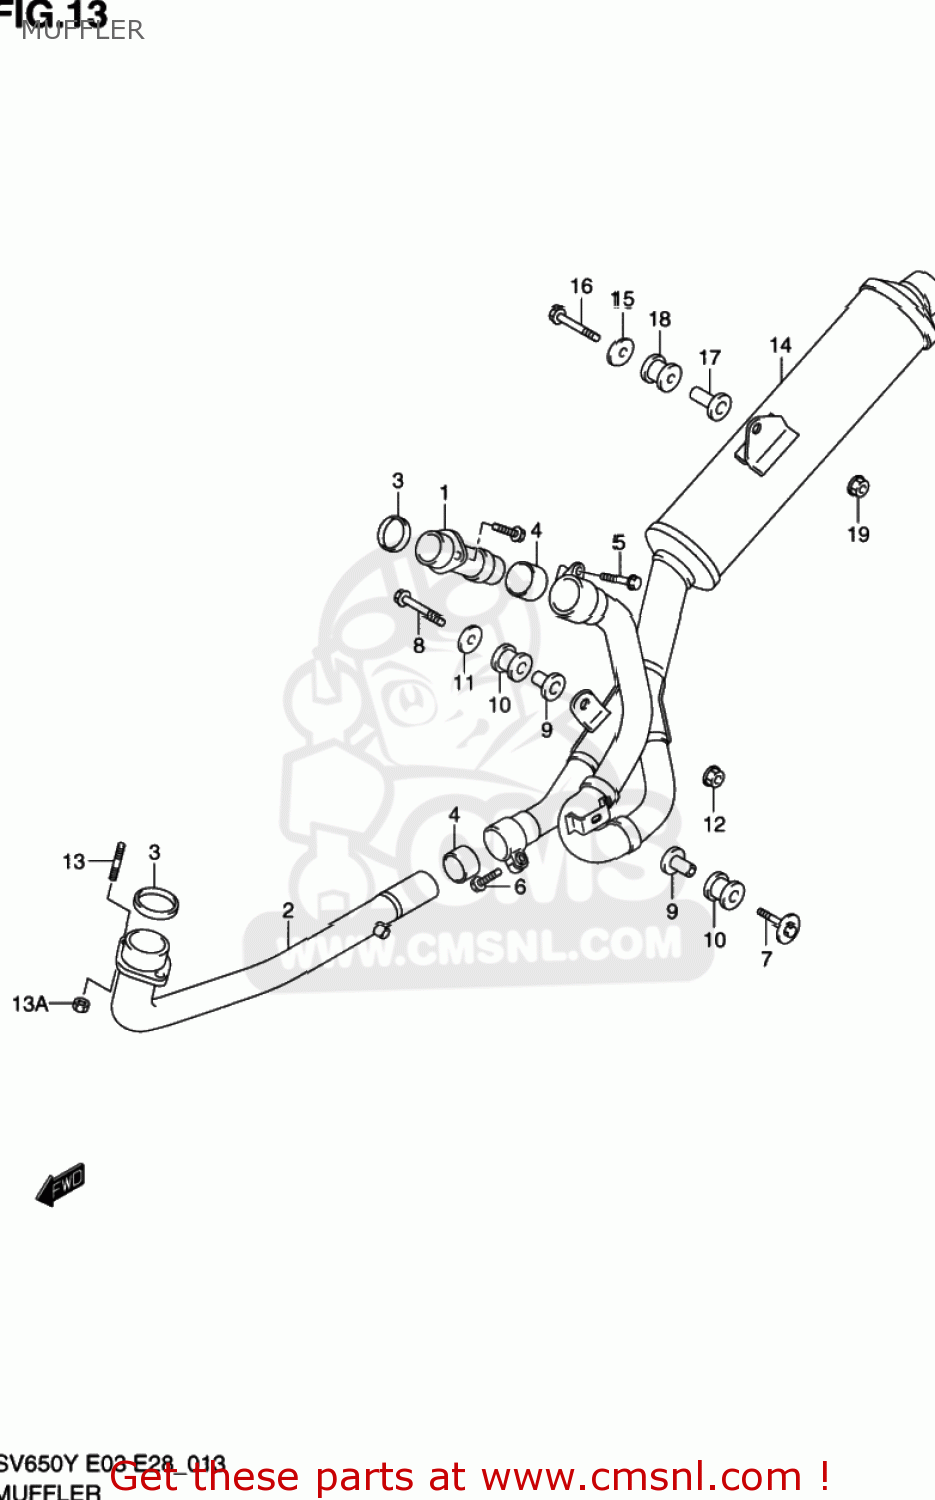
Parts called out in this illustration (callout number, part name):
1	PIPE,EXHAUST RR
2	PIPE,EXHAUST FR
3	GASKET,EXHAUST PIPE (NAS)
4	CONNECTOR,MUFFLER
5	BOLT
6	BOLT
7	BOLT 8X40
8	BOLT
9	SPACER(8.6X12X24.2)
10	CUSHION
11	WASHER (8.5X30X2.3)
12	NUT
13	STUD 8X25
13A	NUT
14	MUFFLER COMP
15	WASHER (8.5X33X1.6)
16	BOLT
17	SPACER(8.6X12X27.1)
18	CUSHION
19	NUT
